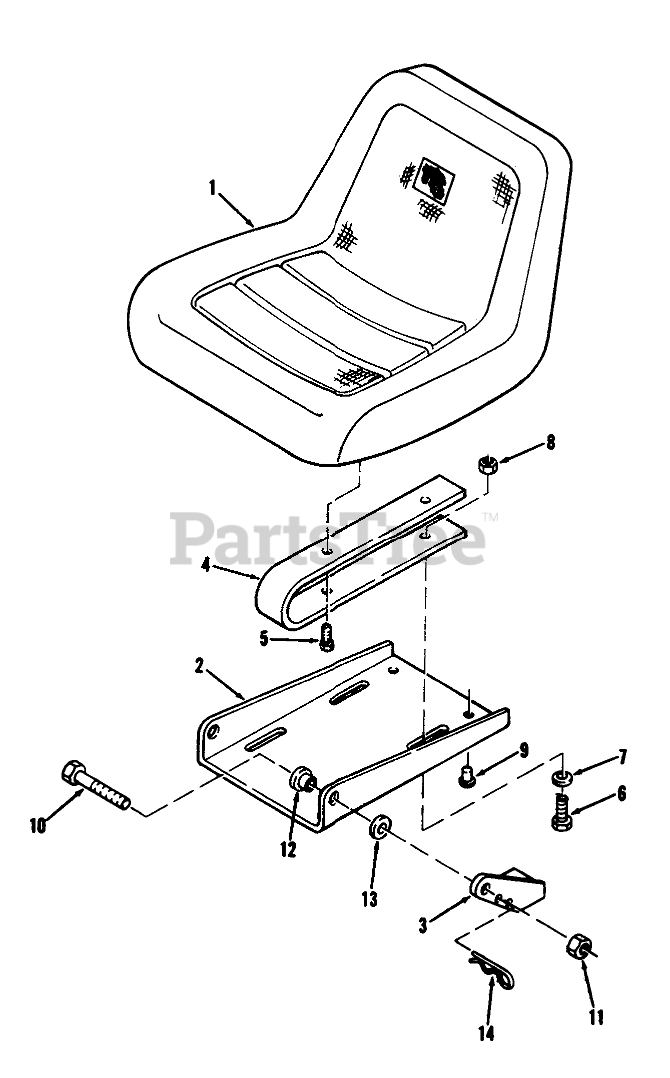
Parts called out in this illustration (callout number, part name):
1	Seat
1	Decal
2	Plate Seat Pivot
2	Decal
3	Bracket-Pivot LH
3	Bracket-Pivot RH
3	Decal-"D-160 Automatic"
4	Seat Spring
5	Bolt
5	Decal
6	HHCS
6	Decal-Caution
7	Lockwasher
7	Decal-Parking Brake
8	Nut
8	Decal-Clutch Knob
9	BUMPER-RUBBER
9	Sleeve
10	Bolt
10	Decal-Tach-a-matic
11	Nut
11	Decal-Maintenance
12	BUSHING
13	WASHER 5/16 SAE
14	Hairpin Cotter
